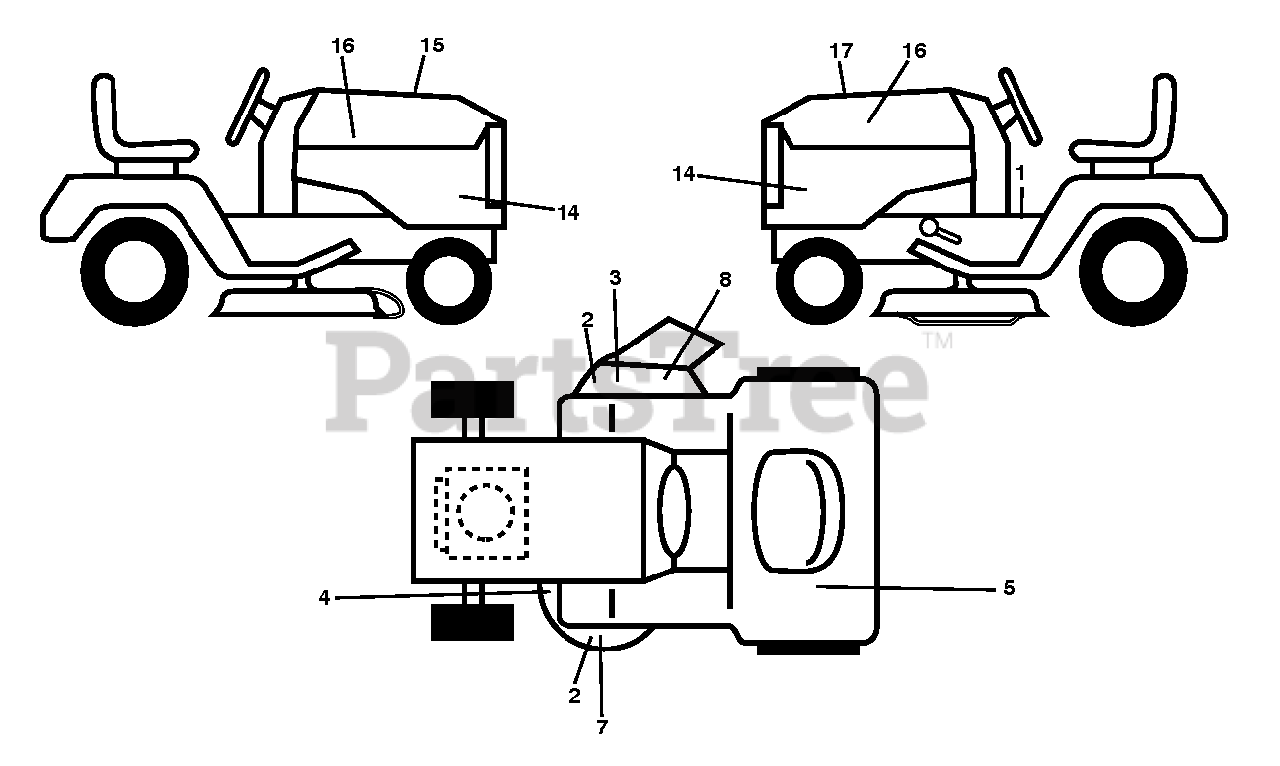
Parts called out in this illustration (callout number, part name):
1	DECAL.FENDER.WARNING.ENGLISH
2	DECAL.DECK.CLEARCUT.NOSTEP
3	DECAL BELT ROUTING DECAL DECAL
4	Deck Decal, WA
5	DECAL.RESERVEFUELSELCTR.ENG
7	DECAL DECK DECAL DECAL.54DECK.
8	DECAL.TRACT/ZTR.DECKWARN.HUSQ
14	Tractor Side Panel Decal
15	DECAL.WARNING.CUST.RESP.E85.
16	DECAL.BADGE.170MM.TEXTLOGO.
17	Decal, Replacement Kawasaki FR7 TLB 54F
